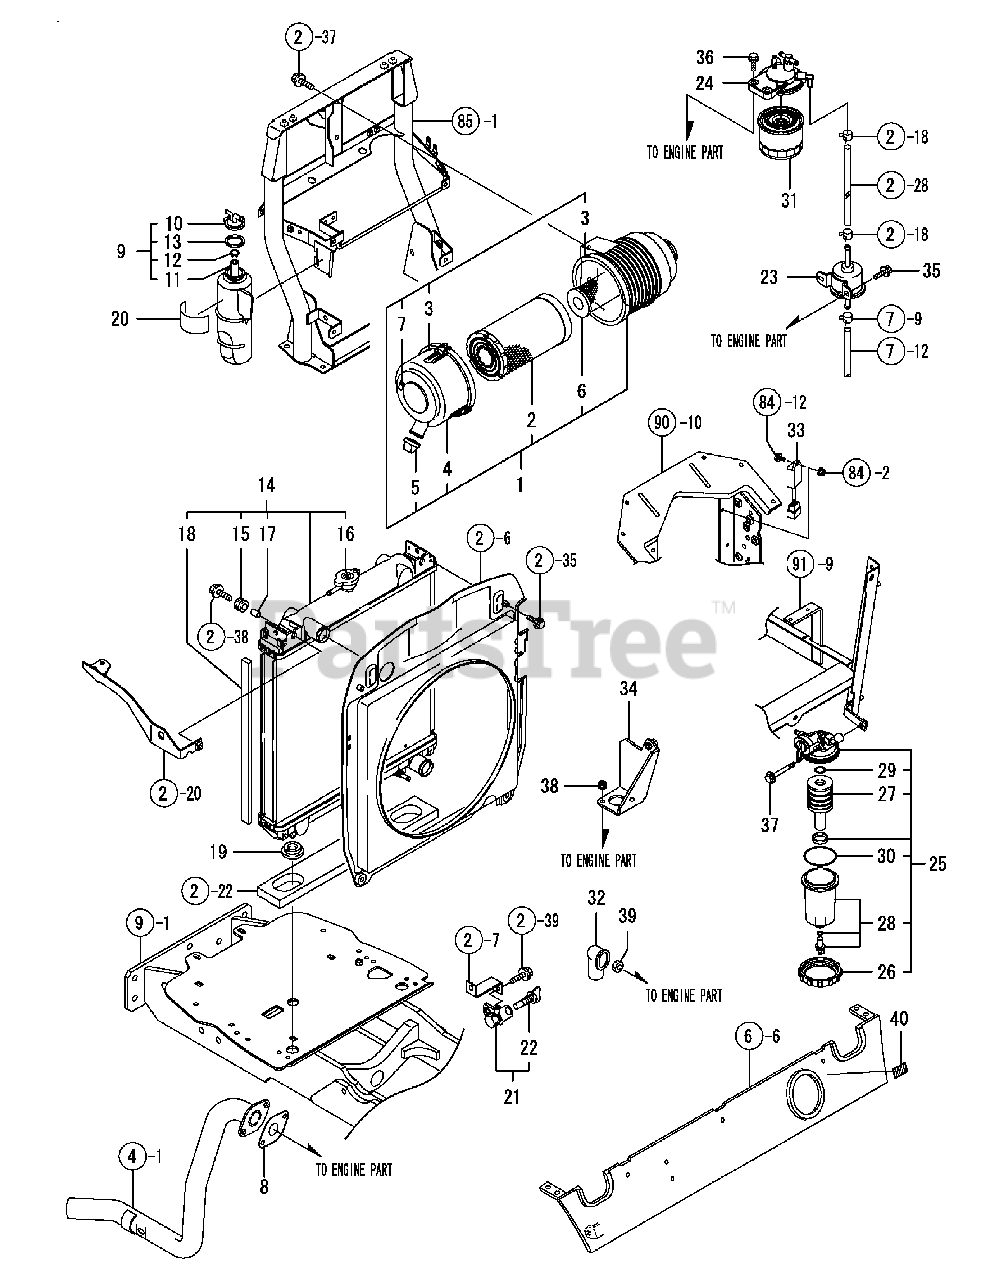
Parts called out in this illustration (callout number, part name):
1	CLEANER ASSY, AIR
2	ELEMENT 6, CLEANER
5	VALVE, UNLOADER
6	ELEMENT ASSY,INNER
9	TANK ASSY, SUB
18	SEAL, RADIATOR
20	LABEL,SUB-TANK
21	PETCOCK ASSY, 2-WAY
22	PETCOCK, DRAIN
23	PUMP ASSY, FUEL FEED
24	BRACKET, FUEL FILTER
25	SEPARATOR ASSY
26	RING, RETAINING
27	ELEMENT, FUEL SEPARATOR
29	O-RING 1A P-16.0
30	O-RING 1A G-65.0
32	COVER, TERMINAL
33	TIMER, FUEL SOLENOID 1 SEC
35	BOLT M 6X 12 PLATED
36	BOLT M 8X 30 PLATED
37	BOLT M 8X 70 PLATED
40	LABEL, FUEL OIL
